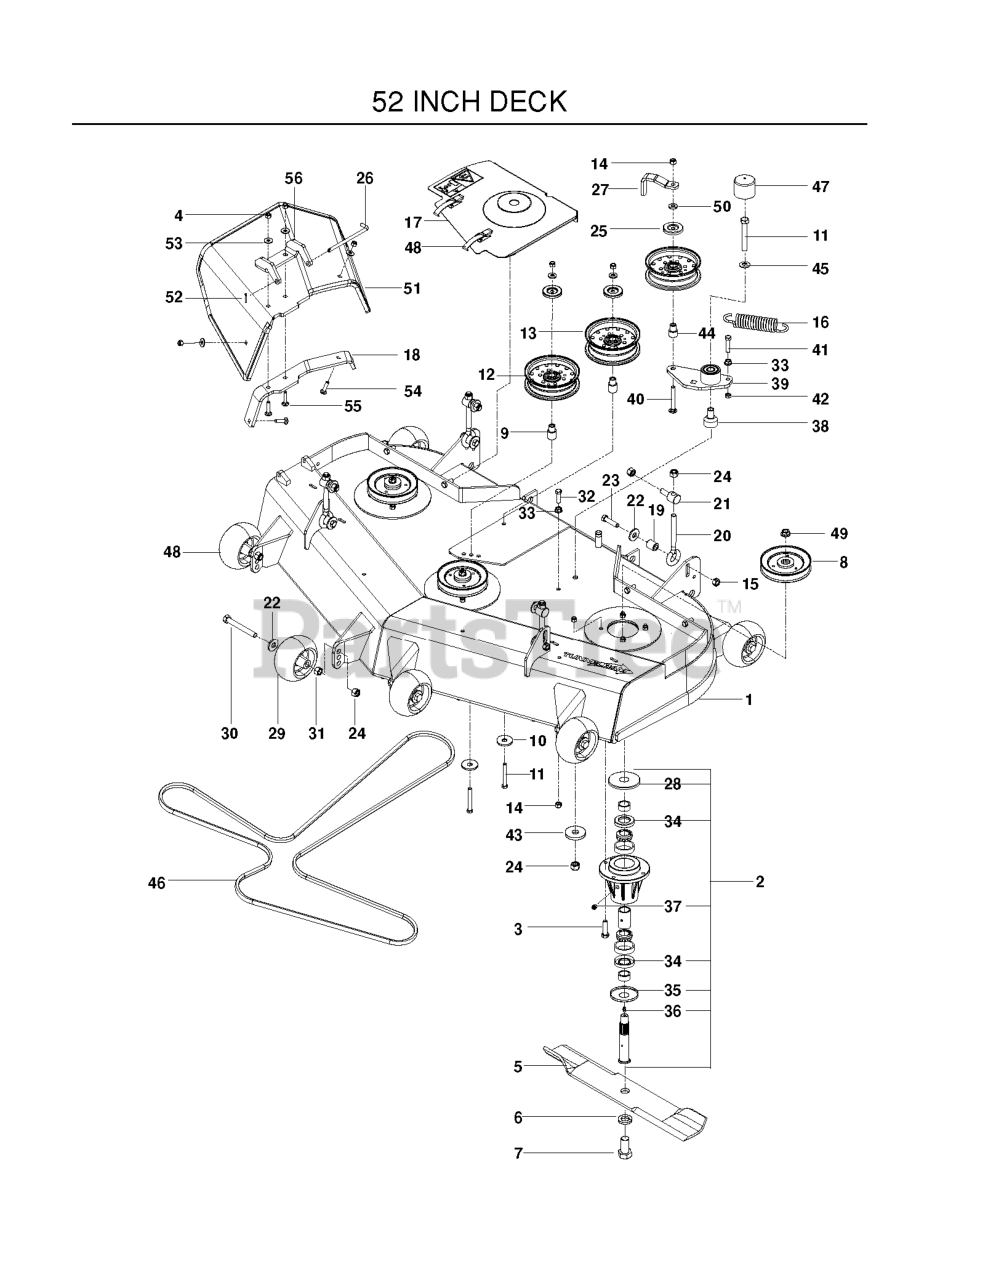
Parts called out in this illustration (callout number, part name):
1	DECK W/DECALS 52" HUS
2	HOUSING ASM, 52/61
3	HCS 5/16C X 1 1/4
4	NUT 5/16 NYLOC
5	BLADE OEM 18"
6	LOCKWASHER 5/8
7	HCS 5/8F X 1 1/4
8	PULLEY, 52
9	IDLER BUSHING
10	SPINDLE WASHER
11	HCS 1/2C X 3 1/4
12	IDLER PULLEY
13	PULLEY - IDLER, 6IN WIDE
14	NUT 3/8-16 NYLOC
15	NUT 7/16C CENTERLOCK
17	52" BELT SHIELD ASM - RH
17	52" BELT SHIELD ASM - LH
18	BRACKET, REINF-CHUTE
21	SWIVEL, DECK HEIGHT ADJ
22	WASH USS FLAT 1/2
23	HCS 7/16 - 14 X 1 3/4
24	NUT 1/2-13 HEX NYLOC ZD
25	DUST SHIELD
26	PIN, CHUTE PIVOT
28	TOP DUST CAP
29	GAUGE WHEEL
30	HCS 1/2-13 X 4 GR 5 ZD
31	NUT 1/2 HEX JAM
32	HCS 3/8C X 1 1/4 GR5
33	NUT 3/8C WHIZ
34	SHAFT SEAL
35	BOTTOM DUST CAP
36	PLUG-VENTED
38	PIVOT, BEARING
39	ARM-IDLER W/BRG
40	RHSNB 3/8-16 X 2.75
41	HCS 3/8-16 X 1-1/2
42	NUT 3/8-16 HEX JAM
43	WASHER, SUPPORT
44	BUSHING, IDLER
45	CONTACT BELLSPR 1/2
46	BELT, DECK
47	CAP, VINYL
48	DRAW LATCH
49	NUT FLANGE 3/4-16
50	WASHER, 3/8 THICK
51	CHUTE, RUBBER DISCHARGE 52/61"
52	RP_COTTER PIN 1/8 X 3/4
53	WASHER 5/16 FLAT
54	BOLT, CARRIAGE 5/16X1-1/4
55	RHSNB 5/16-18 X 1-1/2 GR 5 ZD
56	PIVOT BRACKET - RUBBER CHUTE
